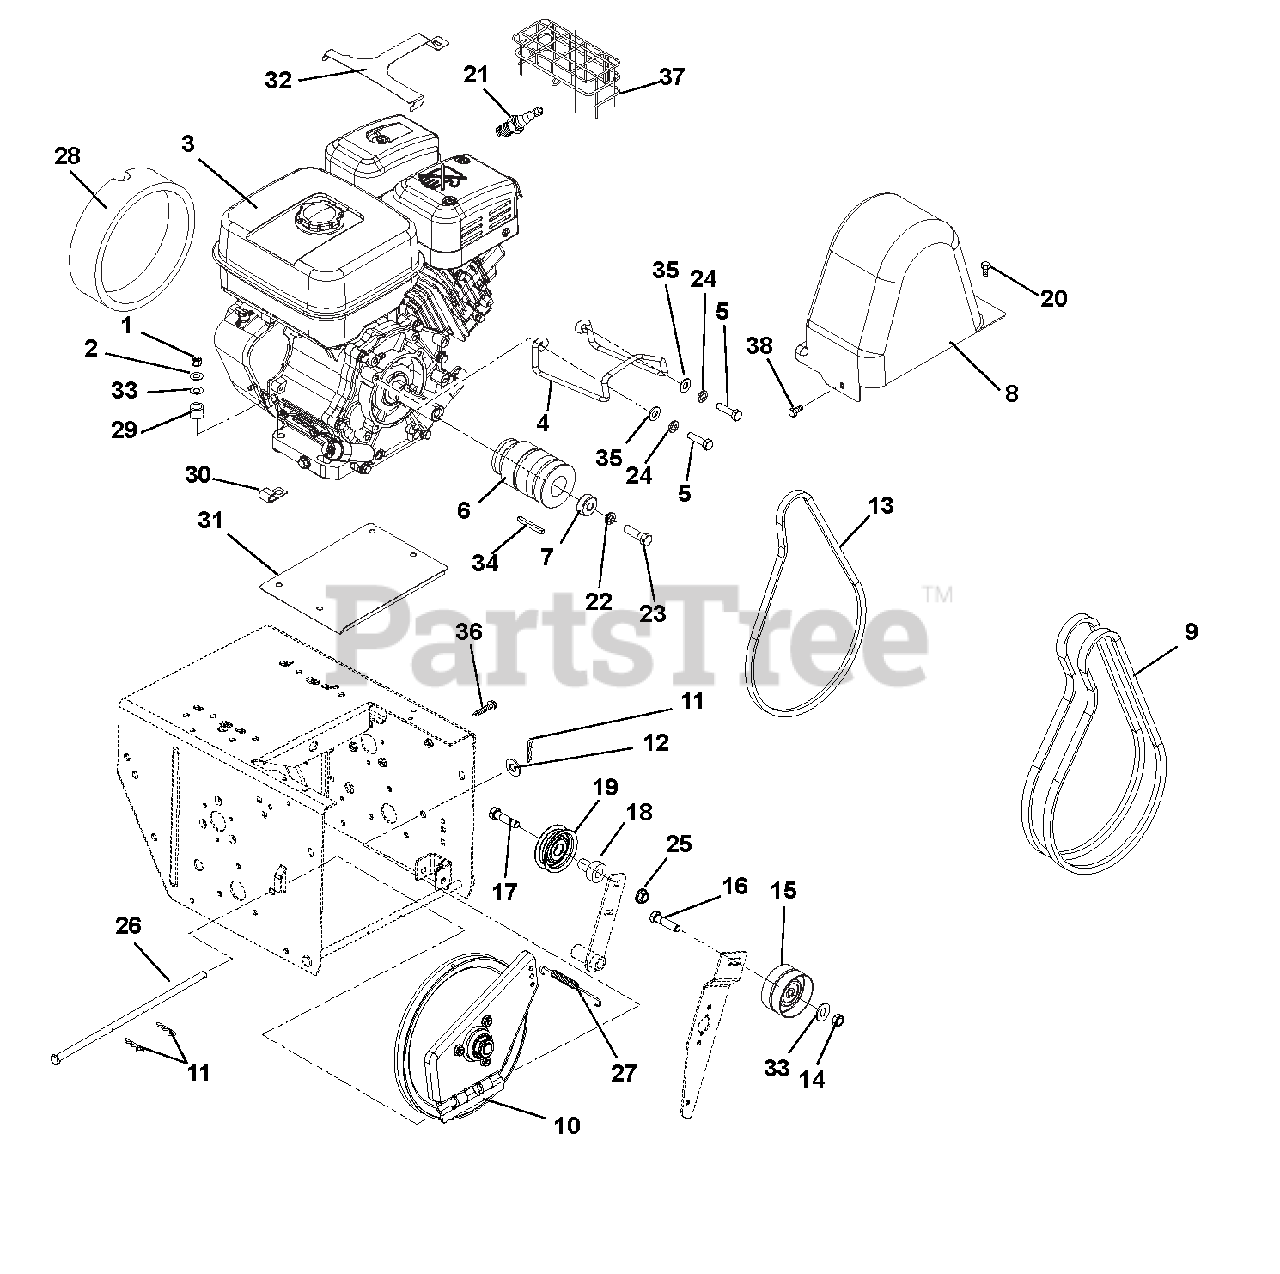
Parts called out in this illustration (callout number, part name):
1	@NUT-HEX .31-18 YWZC
2	WSHR-LK .312X.097 HVY YWZC
3	ENGINE,SUBARU EX27 AS 120V
4	FINGER, BELT
5	BLT-HEX .31-24X.75 YWZC GR5
6	SHEAVE, SUBARU EX27
7	BSHG-SPACER .47X1.25X.50
8	COVER, BELT-TALL PRO
9	V-BELT, HA-RAW EDGE (SET)
10	PLATE, SWING ASSEMBLY-DEEP
11	PIN-HAIR, ENDRIES #25 YWZC
12	@WSHR-FL-STL.406X.812X.065 YWZ
13	V-BELT, 3L-RAW EDGE
14	@NUT-LK-CTR-JAM .375-16 YWZC
15	IDLER, FLAT-2.75 OD X .375 ID
16	@BLT-RHDSSQNK .38-16X1.75 G5YZ
17	@BLT-HEX .31-18X1.25 GR5 YWZC
18	SPCR, BRG .315X.50X.688X.281
19	IDLER
20	SCR-TAP .25-20X.50 LGHWH TR YZ
21	PLUG, SPARK - TEC. SNO-THRO
22	@WSHR-LK .44X.109 REG YWZC
23	BLT-HEX .44-20X1.50 G5 YZ EP80
24	WSHR-LK .312X.097 HVY YWZC
25	@NUT-LK-TOP-FLG .31-18 YWZC
26	PIN, PIVOT
27	SG-TENS .048X.50X2.8
28	FOAM COVER, RECOIL-SUBARU
29	BSHG-SLV .325X.400X.795
30	J-CLAMP
31	BAFFLE, WATER-PRO SERIES
32	GUARD, SNOW-SUBARU
33	@WSHR-FL-STL.38X.875X.083 YWZC
34	KEY .25X.25X2.25
35	@WSHR-FL-STL.344X.688X.065YWZC
36	@SCR-TAP .25-20X1.50 HWH TR YZ
37	MUFFLER GUARD, SUB EX270JO930
38	SCR-TAP .25-20X.5 CAPTIVE
